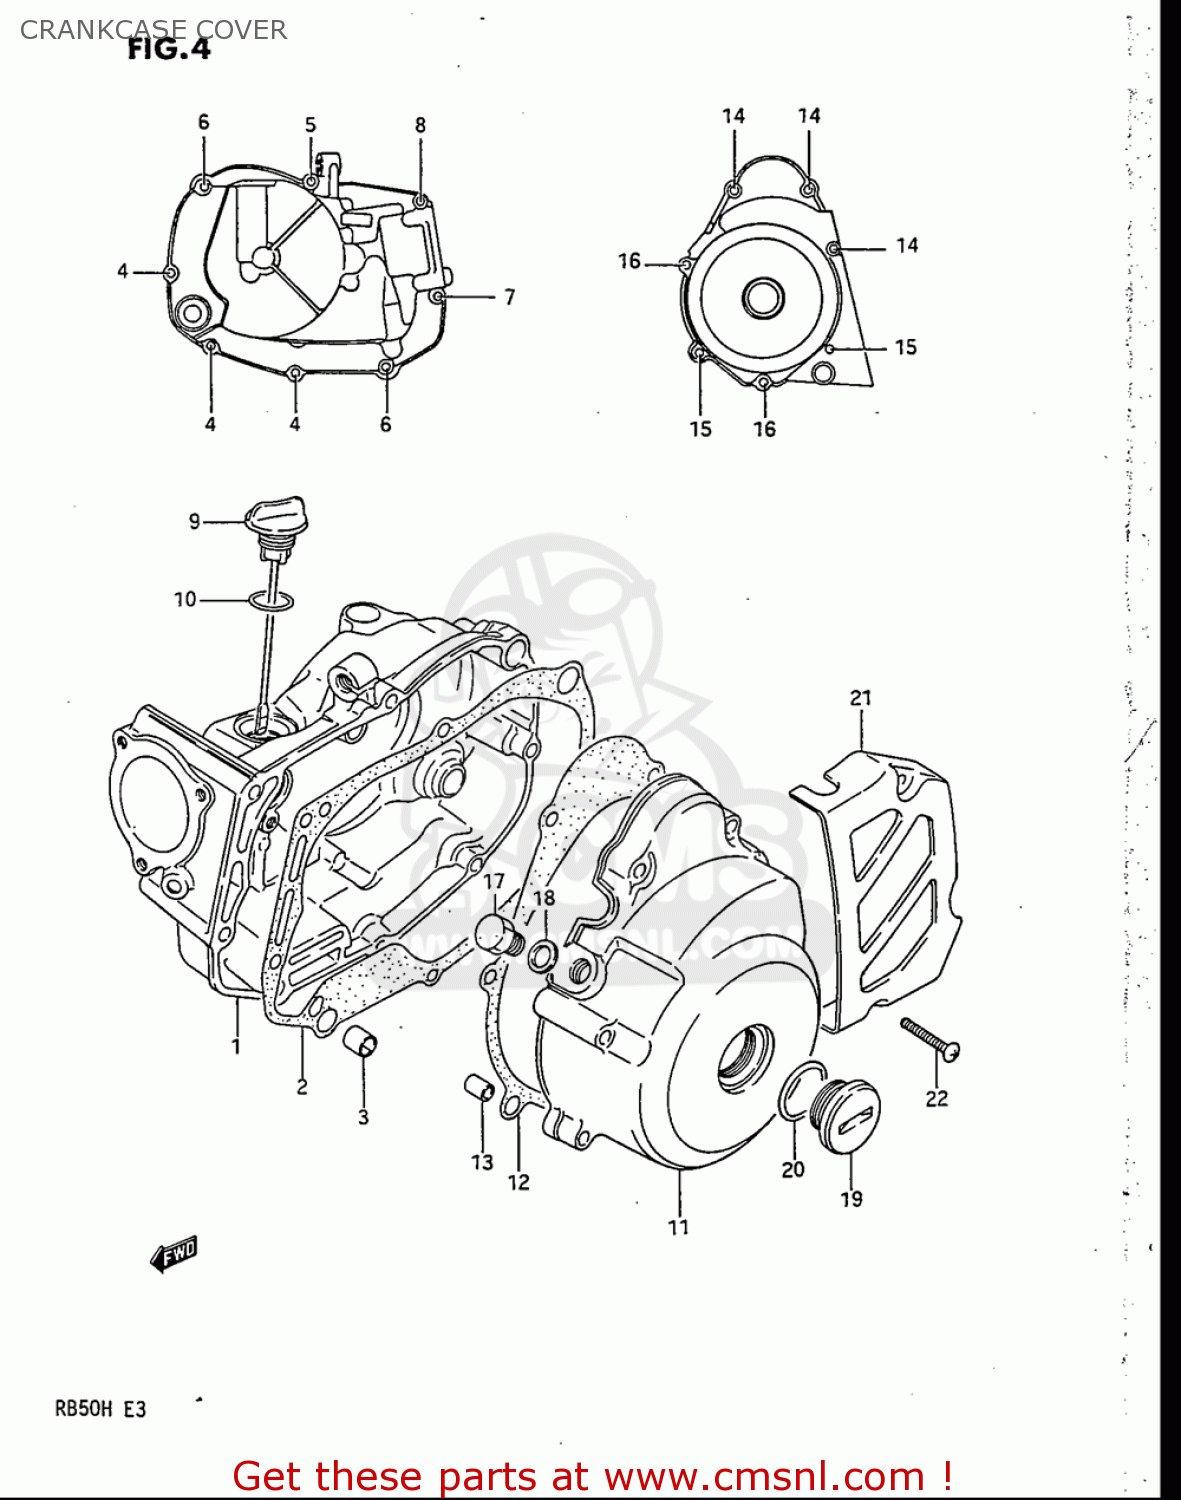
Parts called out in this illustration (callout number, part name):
2	GASKET,CLUTCH COVER (NAS)
3	PIN
4	SCREW
5	SCREW
6	SCREW
7	SCREW
8	SCREW
9	GAUGE,OIL LEVEL
10	O RING(D:3.1,ID:16.8)
11	COVER,MAGNETO
12	GASKET,MAGNETO COVER
13	PIN
14	SCREW
15	SCREW
16	SCREW
17	PLUG
18	GASKET(12.1X16.2X3.7) (NAS)
19	PLUG
20	O RING(D:3.1,ID:22.7)
22	SCREW
